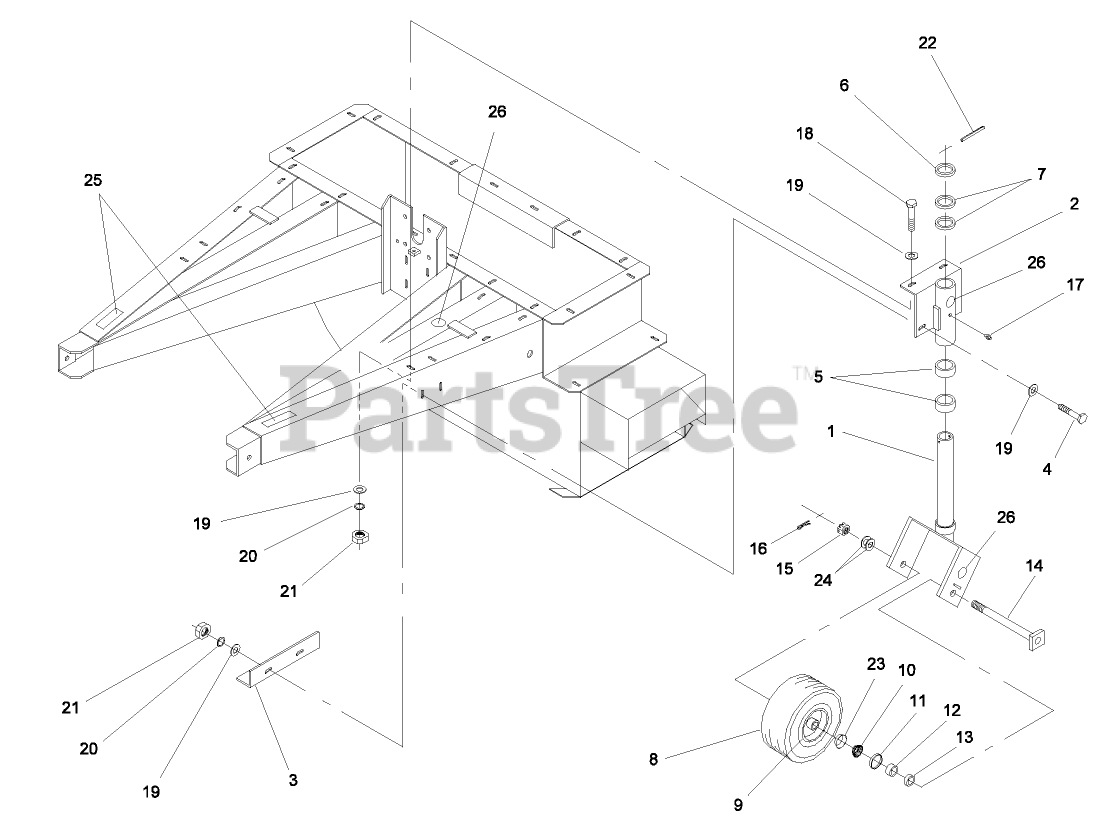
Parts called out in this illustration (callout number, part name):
1	WHEEL YOKE WA
2	WHEEL PIVOT ASY R
3	BACKING PLATE
4	SCREW-HH
5	BOTTOM YOKE SPACER
7	MACHINERY BUSHING
8	TIRE ONLY
9	WHEEL ONLY
10	BEARING-CONE
11	Seal
12	SPACER-AXLE
13	WHEEL SPACER
14	YOKE AXLE ASSY
15	NUT-SLOTTED
16	PIN-COTTER
17	ZERK
18	SCREW-HH
19	WASHER-FLAT
20	WASHER-LOCK
21	NUT-HEX
22	PIN-ROLL
23	Bearing Race
24	MACHINERY BUSHING
25	DECAL- NO RIDERS
26	DECAL-GREASE
